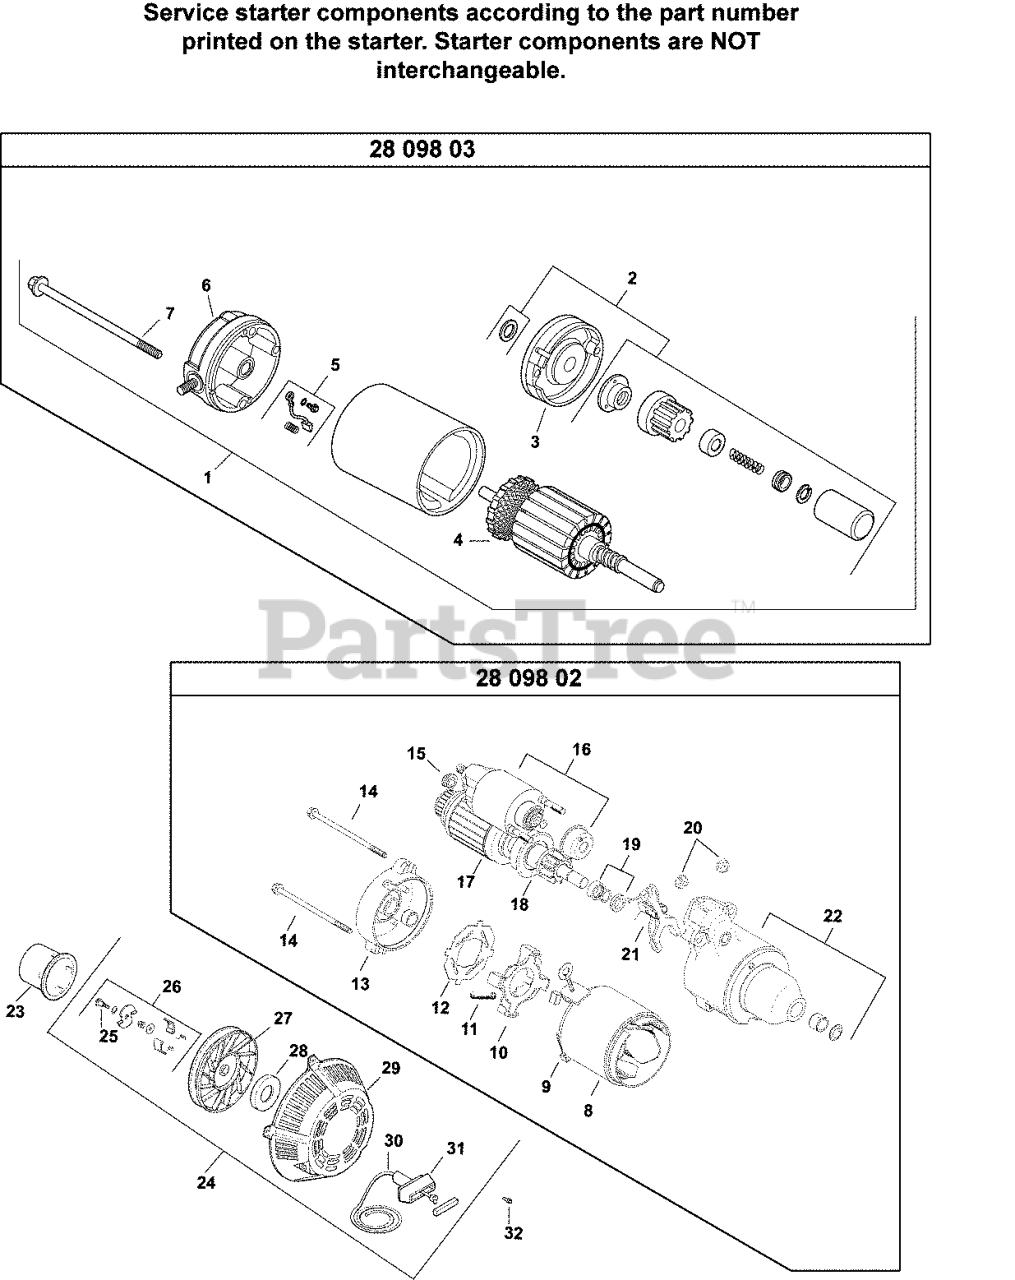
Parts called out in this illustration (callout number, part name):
1	KIT, STARTER - (#DSC)
2	KIT, DRIVE
3	CAP, DRIVE
4	ARMATURE ASSY - DISCONTINUED
5	KIT, BRUSH & SPRING - DISCONTINUED
6	CAP, COMMUTATOR (#DSC)
7	THRU BOLT
8	FRAME W/BRUSHES - DISCONTINUED
9	BRUSH & SPRING KIT
10	BRUSH HOLDER
11	SPRING, BRUSH
12	INSULATOR
13	CAP, COMMUTATOR END
14	THRU BOLT
17	ARMATURE-DISCONTINUED
18	CLUTCH ASSEMBLY-DISCONTINUED
19	KIT, STARTER REPAIR
21	LEVER, STARTER DRIVE
22	HOUSING ASSEMBLY - DISC.
24	STARTER ASSY,RETRACTABLE-USE 12 165 03-S
25	SCREW - DISCONTINUED
26	KIT, DOG REPAIR - (#DSC)
27	PULLEY - (#DSC)
28	SPRING & KEEPER - (#DSC)
29	HOUSING - DISCONTINUED
30	ROPE - DISCONTINUED
31	HANDLE, RECOIL STARTER
32	SCREW, SELF-TAPPING - DISC.
